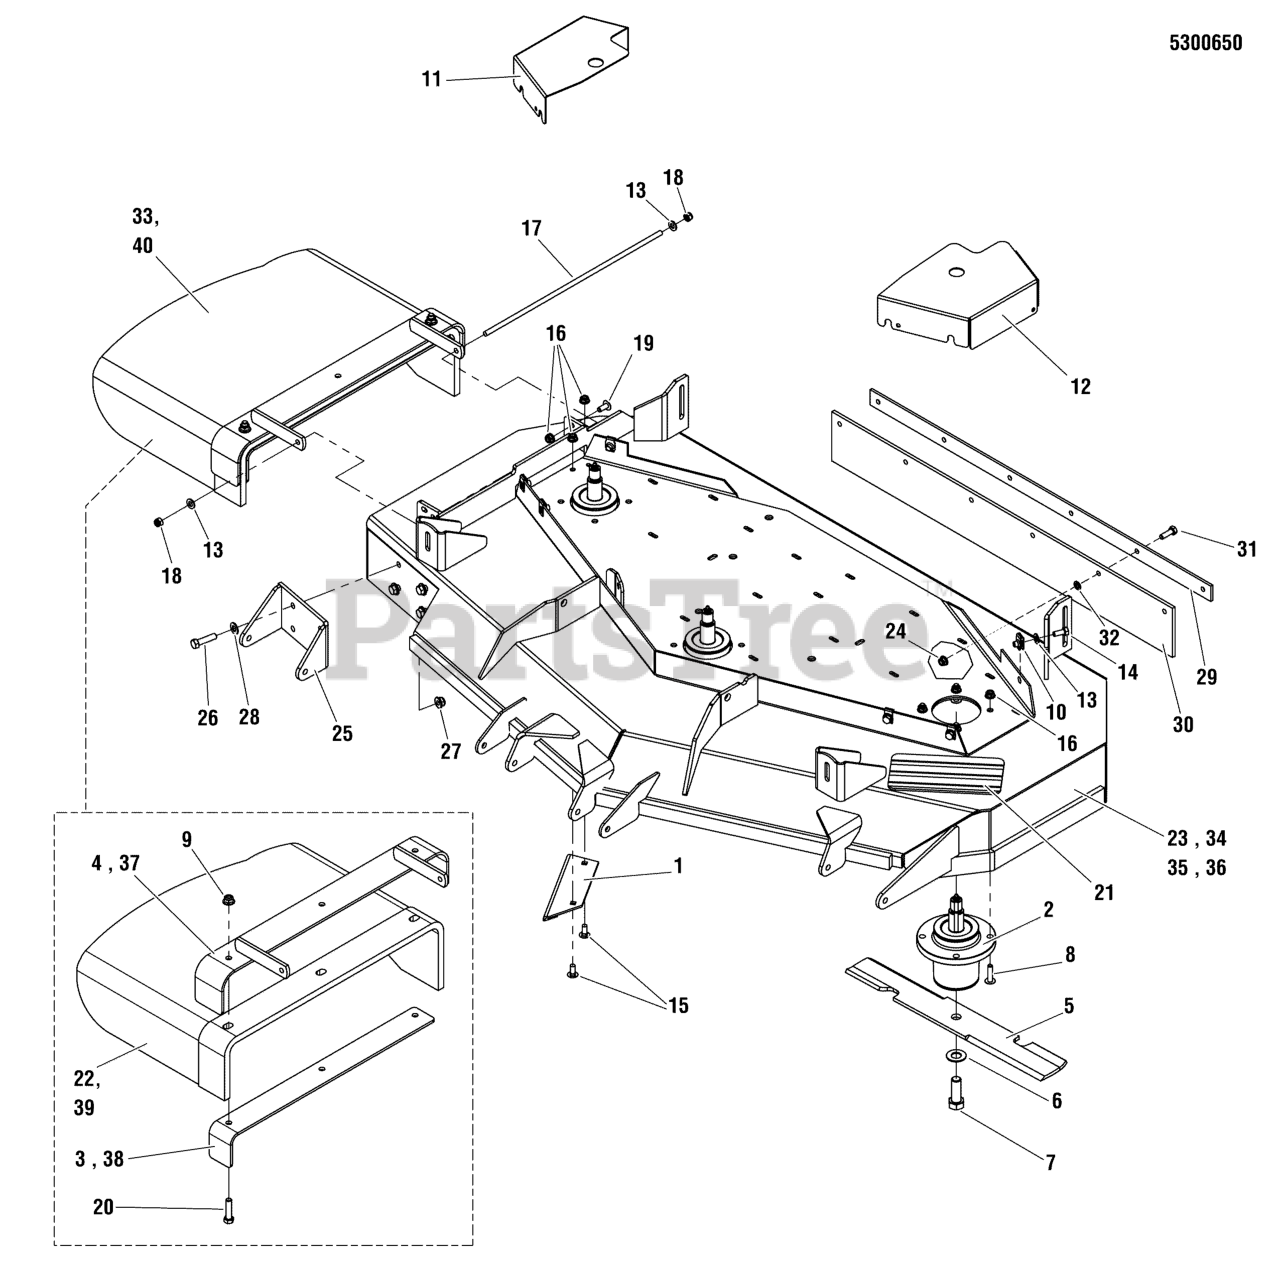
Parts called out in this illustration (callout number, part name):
1	PLATE, DEFLECTOR, 52" - BLK
2	ASSM, SPINDLE, LOW PROFILE
3	SUPPORT, DISCHARGE CHUTE - BLK
4	WELD, FRAME, CHUTE, 61 - RED
5	BLADE, 18 X .25 X 2.5, 1 X 3.5 (SET OF THREE)
6	WASHER, 5/8 GRADE 8, YZ
7	BOLT, 5/8-11 X 1-3/4 GD8
8	BOLT, 5/16-18 X 1 1/4 FLANGE
9	NUT, 3/8-16 HEX NYLOCK FLANGE
10	BODY CLIP, 5/16-18-7GA MATERIAL
11	GUARD, 52" DECK, IS2000, RH - RED
12	GUARD, 52" DECK, IS2000 - LH - RED
13	WASHER, 5/16" SAE
14	BOLT, 5/16-18 X 3/4 GD5
15	BOLT, 5/16-18 X 3/4, CARRIAGE
16	NUT, 5/16-18 HEX NYLOCK FLANGE
17	ROD MOUNT, CHUTE 61"
18	NUT, 5/16-24 HEX NYLON LOCK
19	BOLT, 5/16-18 X 3/4 GD5
20	BOLT, 3/8-16 X 1-1/2" GD5 CZ
21	SAFETY WALK, 4.00 X 7.50
22	CHUTE, DISCHARGE, RUBBER, 61/72, BENT
23	DECK SHELL W/ DECALS,200052SD,DOM716&DWN
24	NUT, 5/16-18 HEX NYLOCK FLANGE
25	PLATE, BRACKET, ANTI SCALP - RED
26	BOLT, 3/8-16 X 1-1/2" GD5 CZ
27	NUT, 3/8-16 HEX NYLOCK FLANGE
28	WASHER, 3/8 SAE
29	PLATE, SUPPORT - BLK
30	FLAP, STRIPER, 52 DECK
31	BOLT, 5/16-18 X 1 GD5 YZ
32	5/16 PUSH-ON NUT RETAINER, STL, CZ
33	PURCHASE INDIVIDUAL REPLACEMENT PARTS
34	DECK SHELL W/DECALS,200052SD,EXP716&DWN
35	DECK SHELL W/DECALS,200052SD,DOM717&UP
36	DECK SHELL W/DECALS,200052SD,EXP717&UP
37	WELD, FRAME, CHUTE, 52 - BLK
38	SUPPORT, DISCHARGE CHUTE, 52 - BLK
39	CHUTE, Discharge
40	KIT, DISCHARGE CHUTE, 52" - RED
